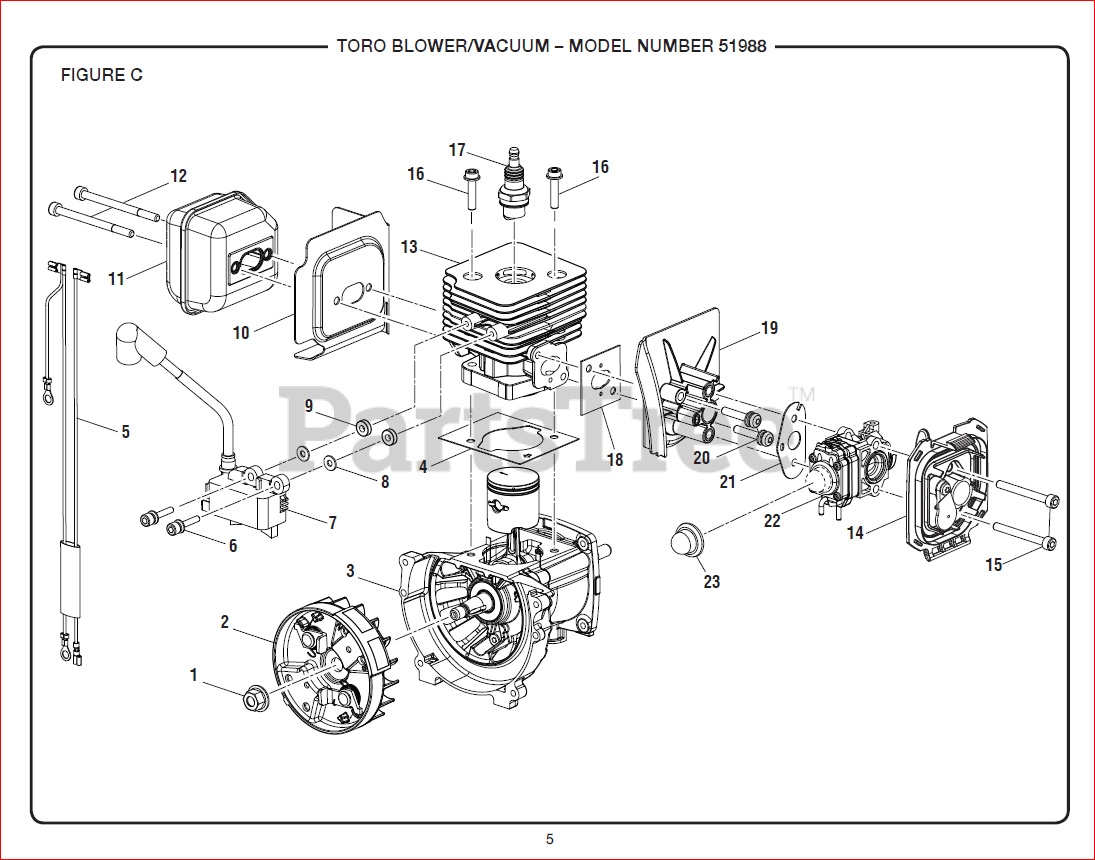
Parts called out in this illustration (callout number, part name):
1	Flange Nut (M8, Flywheel)
2	Flywheel Assembly
3	Crankcase and Piston Assembly
5	Wire Harness
6	Screw (M4 x 22 mm, T20 Torx Slotted Recessed Pan Hd.)
7	Ignition Module
8	Flat Washer (OD10 x ID42 x 1t)
9	Phenolic Spacer (Ignition Module)
10	Muffler Gasket
11	Muffler Assembly
12	Cap Screw (M5 x 65 mm, T25 Torx Soc. Hd.)
14	Air Box Cover Base Assembly
15	Cap Screw (M5 x 45 mm, T25 Torx Soc. Hd.)
16	Screw (M5 x 22 mm, T25 Torx Soc. Hd.)
17	SPARK PLUG CHAMPION - RCJ-6Y
18	Cylinder Gasket
19	Heat Sink
20	Screw w/Washers (M5 x 30 mm, T25 Torx Pan Hd.)
21	Gasket Carb-Heat Dam
22	Carburetor Assembly
23	Purge Bulb
